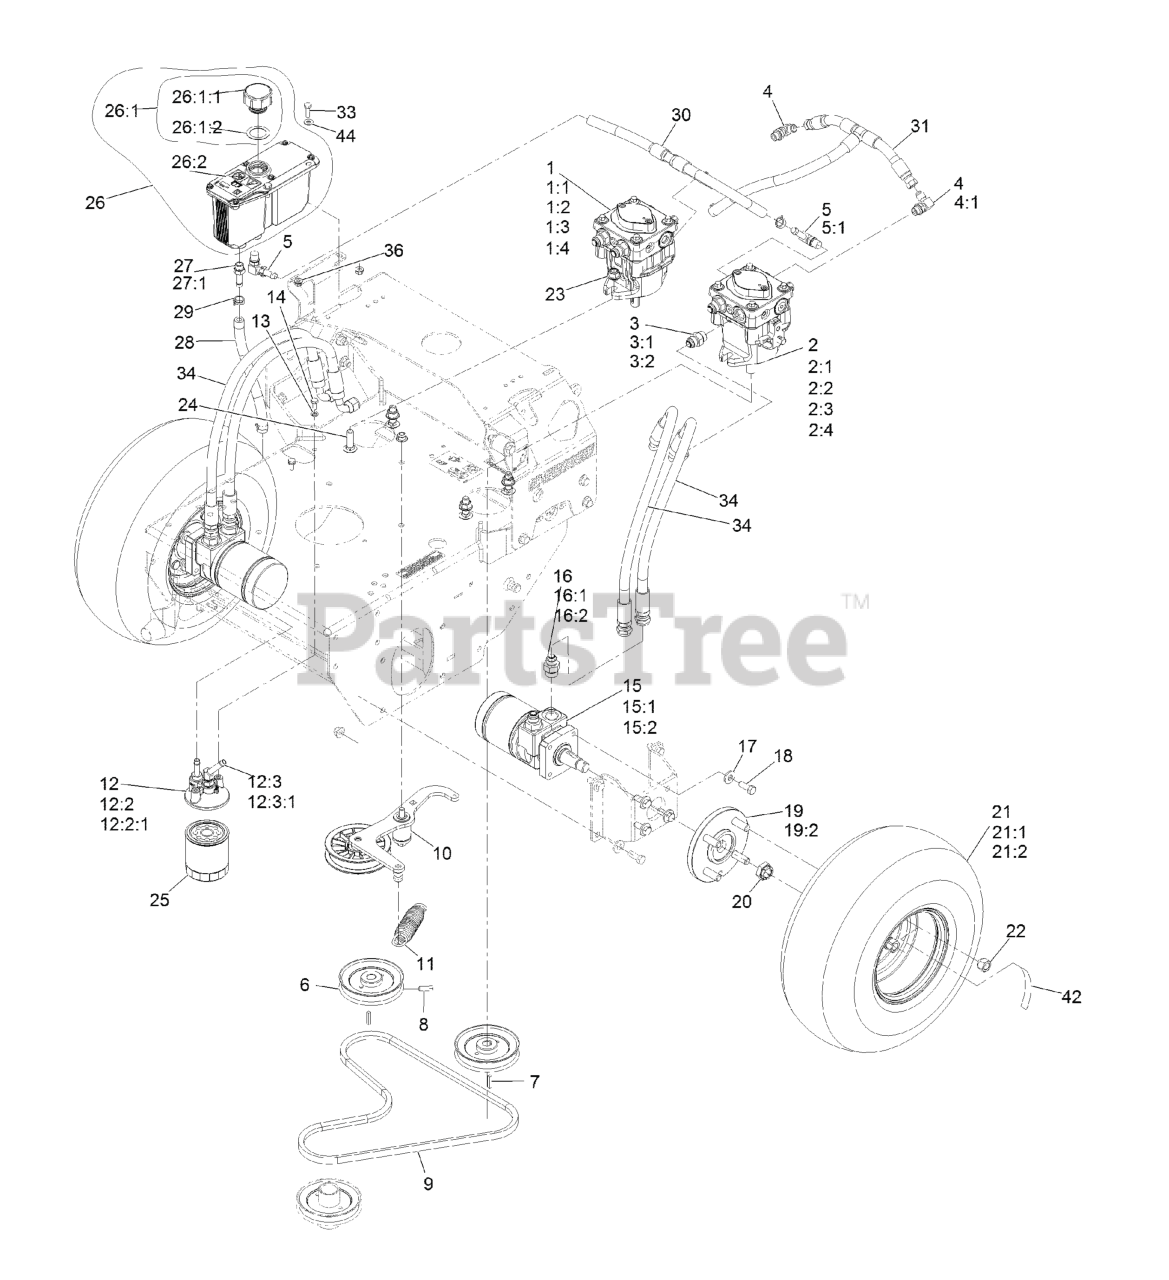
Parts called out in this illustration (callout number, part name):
1	RH HYD PUMP ASM
1:1	INPUT SHAFT KIT
1:2	BEARING-THRUST
1:3	CYLINDER BLOCK KIT
1:4	SEAL OVERHAUL KIT
2	LH HYD PUMP ASM
2:1	INPUT SHAFT KIT
2:2	BEARING-THRUST
2:3	CYLINDER BLOCK KIT
2:4	SEAL OVERHAUL KIT
3	FITTING-STRAIGHT
4	FITTING-ELBOW, 90 DEG
4:1	O-RING
5	FITTING-ELBOW, 90
5:1	O-RING
6	SHEAVE ASM
8	SCREW-SET, SQH
9	BELT
10	ASM, PUMP IDLER
11	SPRING-EXTENSION
12	ASM, FILTER HEAD
12:2	ADAPTER-STRAIGHT
12:2:1	O-RING
12:3	FITTING-BARBED, 45 DEG
12:3:1	O-RING
13	WASHER-LOCK
14	SCREW-HH
15	HYD MOTOR ASM
15:1	SEAL KIT
15:2	BEARING AND SEAL KIT
16	FITTING-STRAIGHT
16:1	O-RING
17	WASHER-BELLEVILLE
18	SCREW-HH
19	WHEEL HUB ASM
19:2	STUD-WHEEL
20	NUT-LOCK
21	WHEEL AND TIRE ASM
21:1	TIRE-TURFMASTER
21:2	RIM-WHEEL
22	NUT-LUG
23	NUT-HF, NI
24	BOLT-CARR
25	FILTER-25 MICRON, BI-DIRE
26:1	Reservoir-HYD
26:1:1	Cap-Reservoir, HYD
26:1:2	GASKET-CAP
26:2	DECAL-WARNING
27	ADAPTER-STRAIGHT
27:1	O-RING
28	HOSE-CHARGE
29	CLAMP-HOSE
30	HOSE-CASE DRAIN
31	HOSE-CHARGE
33	SCREW-HH
34	HYD HOSE ASM
36	NUT-HHF
42	DECAL-TORQUE WHEEL LUG-HU
44	WASHER-FLAT
